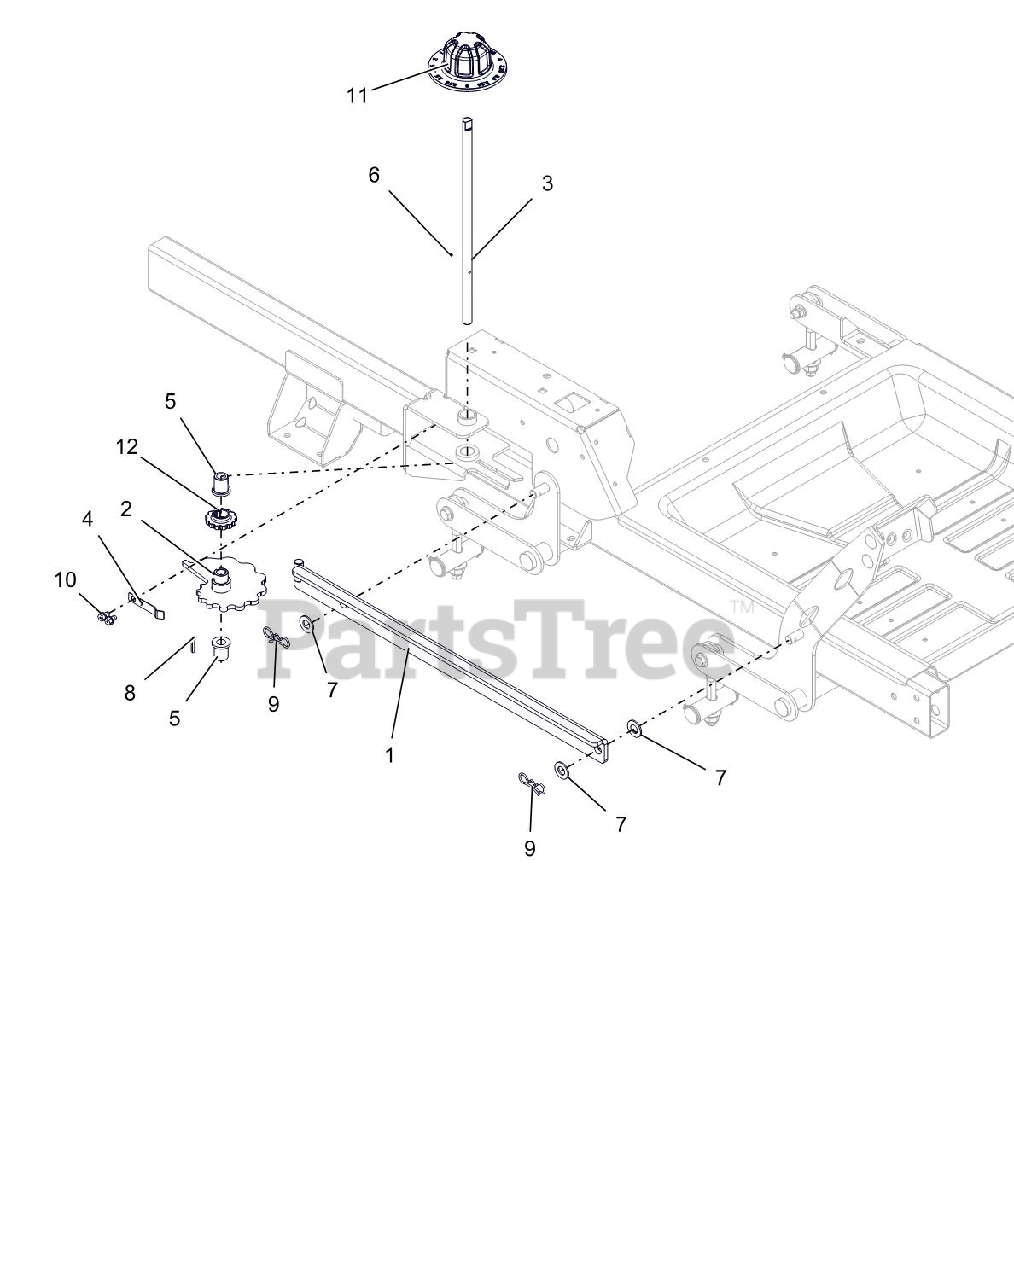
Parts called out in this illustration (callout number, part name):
1	WLDMT, HOC LINK
2	WLDMT, HOC CAM
3	SHAFT, HOC CAM
4	ARM, HOC DETENT
5	BSHG-FLG, .503X.750X.875X1.00
6	PIN-ROLL .125X1.00
7	WSHR-FL-NYL .518X1.000X.080
8	KEY, 1/8 X 1/8 X 1.0
9	PIN,BOW TIE LOCKING .091X1.875
10	@SCR-TAP .25-20X.37 HWH YWZ TR
11	KNOB, HOC
12	GEAR, HOC INDEX
